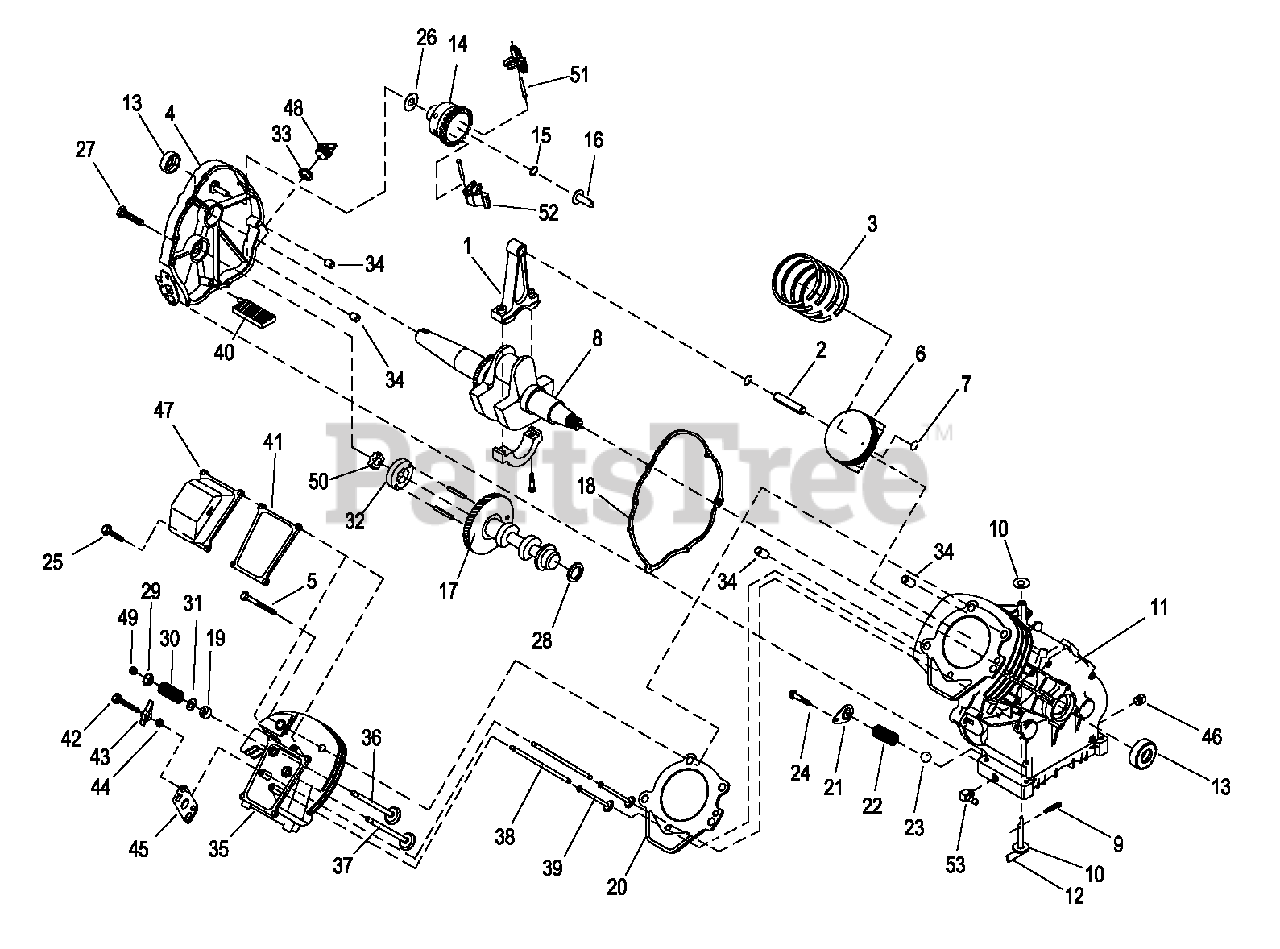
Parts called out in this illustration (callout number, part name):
1	ASSY, CONNECTING ROD
2	PIN, PISTON
3	RING SET, 75 DIAMETER
4	ASSY, GEAR COVER
5	SCREW, HHC M8-1.2 5 X 56
6	PISTON, COATED 75 DIAMETER
7	RETAINER, PISTON PIN
8	ASSEMBLY, CRANKSHAFT
9	PIN COTTER "R" 0.59X1/4X1-1/8
10	WASHER, FLAT 1/4", 0.15 THICK
11	CRANKCASE GH220 HS
12	ARM, GOVERNOR
13	SEAL, 28mm DIA x 41.47 VITON
14	ASSY, GOVERNOR GEAR
15	C-RING, GOVERNOR GEAR RETAIN ING
16	SPOOL, GOVERNOR MACHINED
17	ASSY, C AMSHAFT 220 W/ COMP. RELEASE
18	GASKET, CRANKCASE
19	SEAL, VALVE STEM
20	GASKET, CYLINDER HEAD GH220
21	COVER, OIL PRESSURE RELIEF
22	SPRING, OIL PRESSURE RELIEF GH2 20
23	BALL, 11 /32" DIAMETER PRESSURE RELIEF
24	SCREW, HHTT M5-0 .8 X 10
25	SCREW HHFCS M6-1 X 1 2 G8.8
26	WASHER, THRUST GOVERNOR GEAR
27	SCREW, HHFC M8-1.25 x 3 5
28	WASHER, SPRING
29	RETAINER, VALVE
30	SPRING, VALVE
31	WASHER, VALVE SPRING WEAR
32	GEROTOR, OUTER
33	O-RING, 11/1 6-7-8" 75 DUROMETER VITON
34	SLEEVE, DOWEL PIN 12mm DIAMETER
35	ASSEMBLY, HEAD GUIDES & SEATS 22 0
36	VALVE, EXH AUST
37	VALVE, INTAKE
38	PUSHROD, 1 45.7 6 LENGTH GH2 20
39	TAPPET, 7 .5mm DIAMETER
40	ASSEMBLY, OIL PICK UP GH2 20
41	GASKET, VA LVE COVER
42	STUD, ROCKER ARM PIVOT
43	ARM, ROCKER GH2 20
44	NUT, JAM M-6 – 0.75 FINE THD
45	PLATE, PUSHROD GUIDE
46	PLUG, 1/4" NPTF PIPE
47	ASSEMBLY, VALVE COVER STEEL
48	PLUG, OIL FILL PLASTIC, ORANGE
49	KEEPER, VALVE SPRING
50	GEROTOR, INNER
51	PIN, GOVERNOR FLYWEIGHT RETAINER
52	FLYWEIGHT, GOVERNOR
53	BARBED ELBOW 90 1/4" NPT X 3/8"
